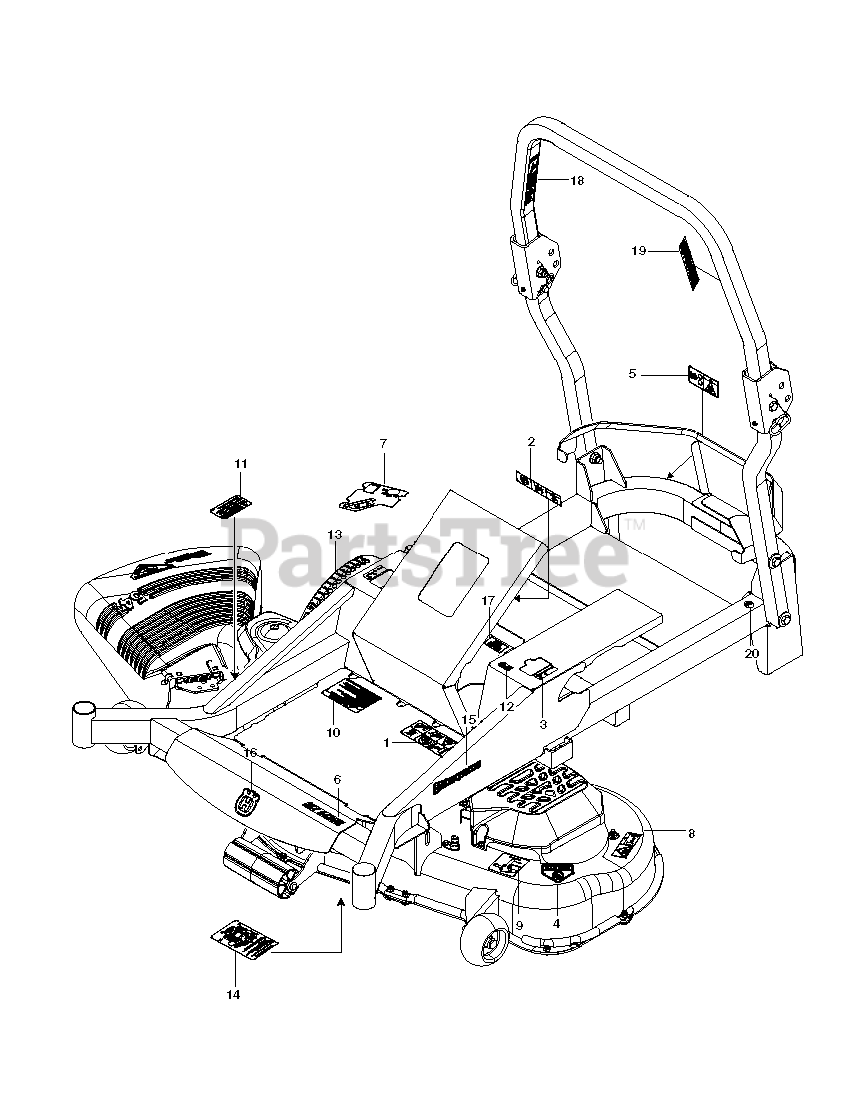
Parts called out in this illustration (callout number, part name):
1	DECAL, WARNING
2	EURO DECAL-BATTERY WARNIN6
3	DECAL, MOTION CONTROL
4	DECAL, CPSC
5	DECAL, BELT DRIVE
6	DECAL, MZ5424S
7	DECAL, CONSOLE HUS
8	DECAL, EURO SEVERING
9	DECAL, BELT ROUTING
10	DECAL, WARNING
11	DECAL, CAUTION
12	DECAL, F.S.T.
13	DECAL, HEIGHT ADJUST
14	DECAL, SERVICE
15	RP.DECAL.BADGE.170MM.TEXTLOGO
16	DECAL.AUGER.HUSQ.CROWN.SNOW
17	DECAL HYDROGEAR ZT-3100
18	DECAL, ROPS, WARNING
19	DECAL ROPS
20	DECAL.E85.WARNING.2012
